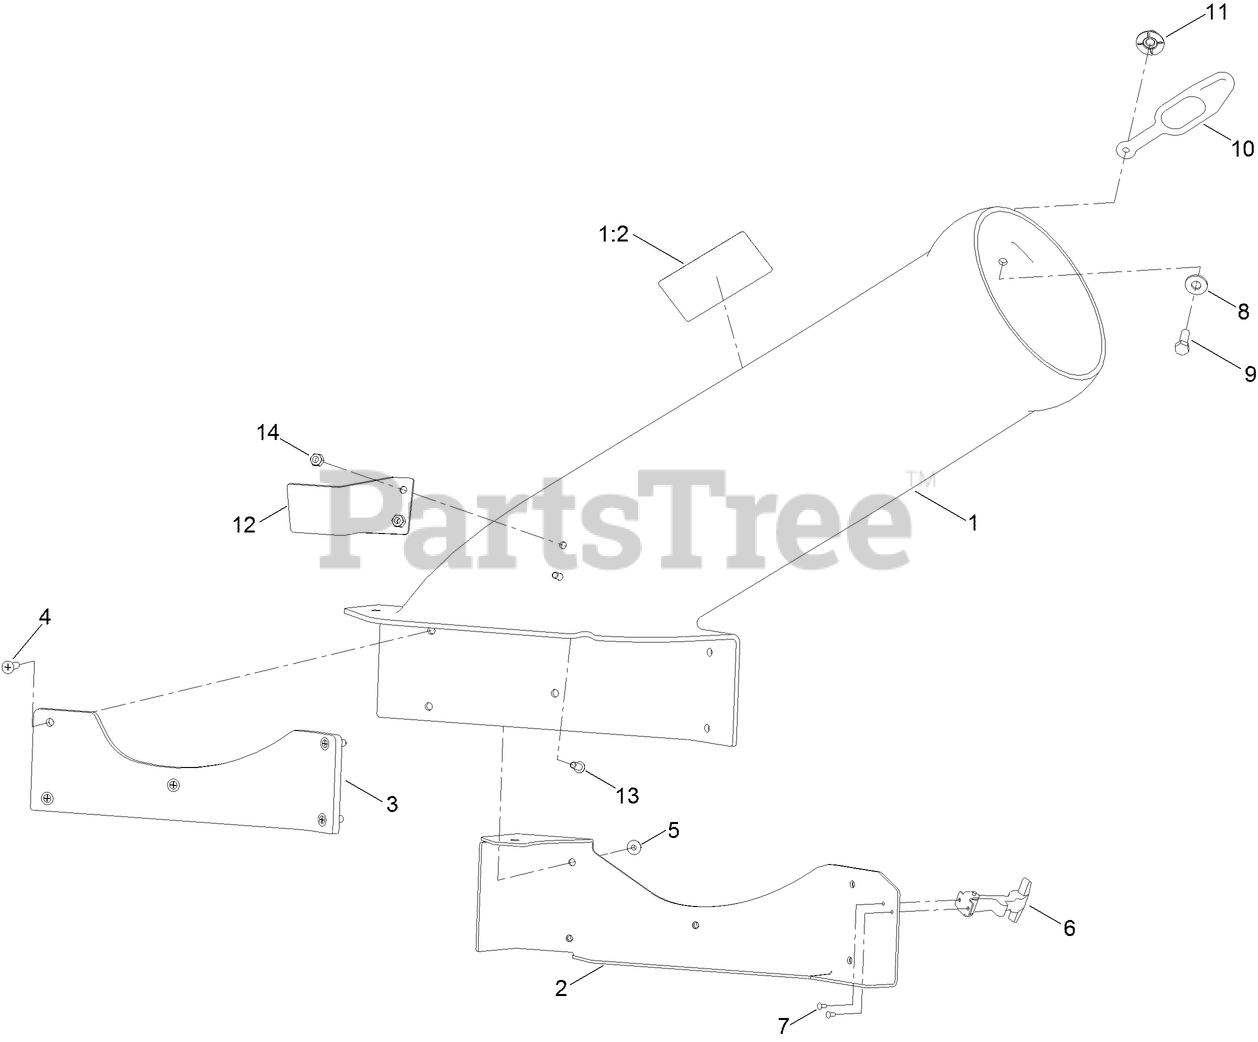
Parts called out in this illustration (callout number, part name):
1	60 IN BAGGER BOOT ASM
1:2	DECAL-DANGER
2	PLATE-COVER, BOOT
3	SPACER-RUBBER
4	SCREW-PFH
5	NUT-HF
6	HANDLE ASM
7	RIVET-POP
8	WASHER-FLAT
9	SCREW-HH
10	RETAINER-DUCT
11	NUT-IMPELLER
12	PROP-DEFLECTOR
13	SCREW-HSBH
14	NUT-HEX
